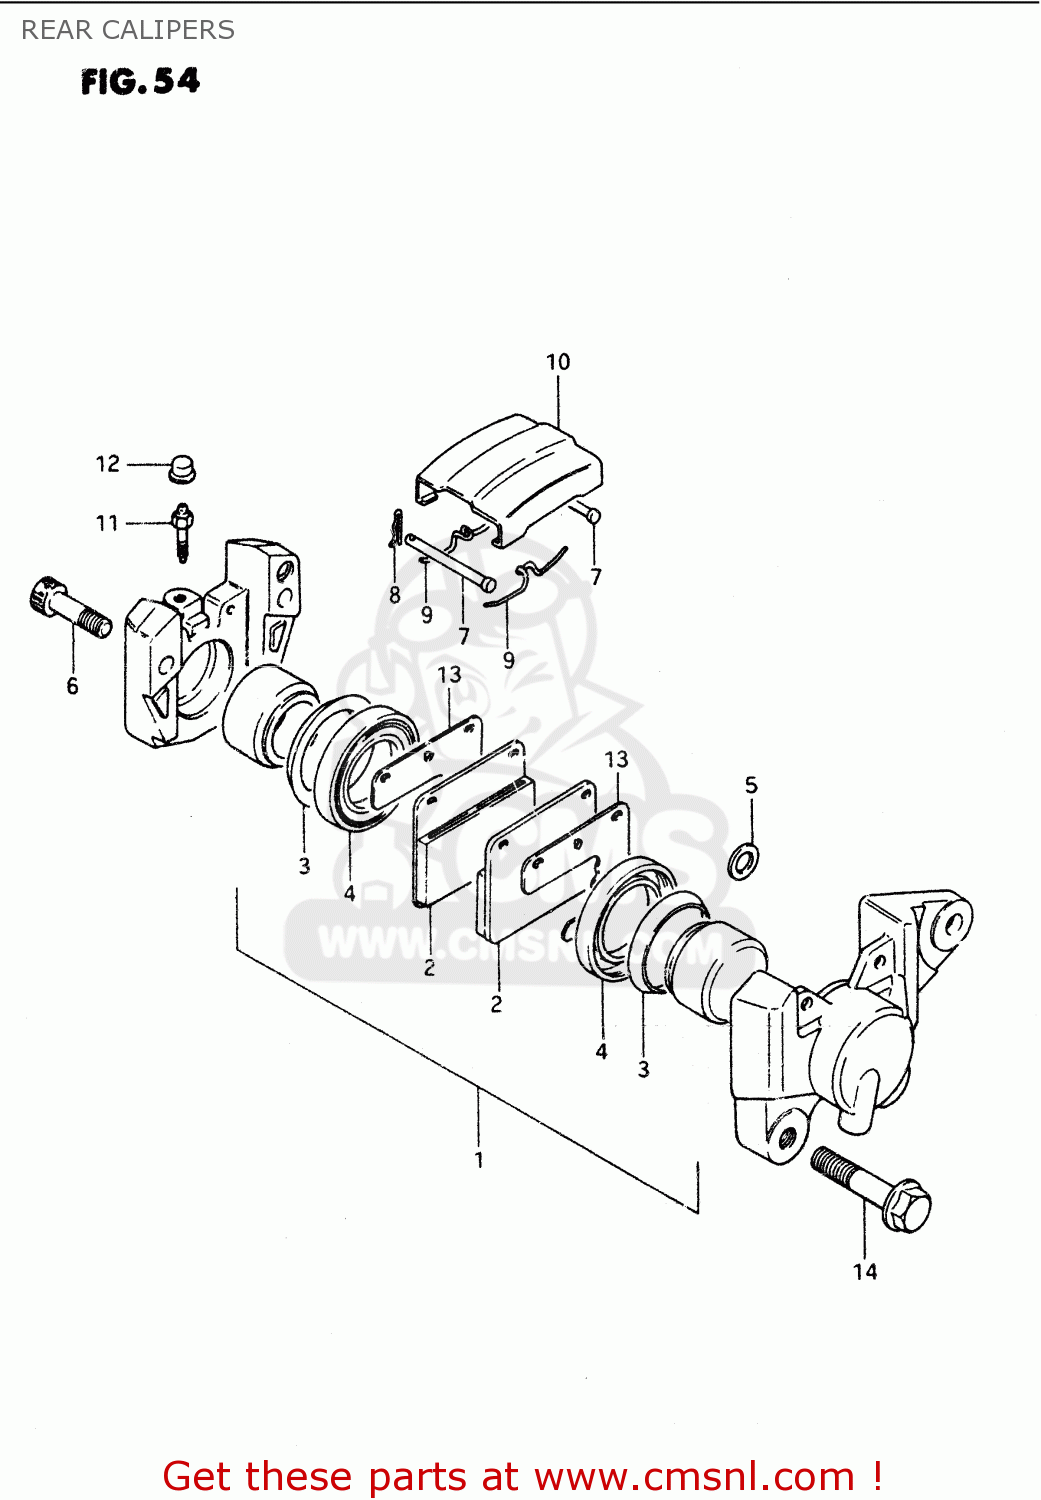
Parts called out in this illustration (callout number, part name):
1	PISTON SET
2	PAD,BRAKE (MCA)
3	SEAL,PISTON
4	BOOT,PISTON
5	SEAL,JOINT
6	BOLT,CALIPER HOUSING
7	PIN,PAD
8	CLIP,PAD PIN
9	SPRING
10	COVER,DUST
11	BLEEDER
12	CAP,BREATHER
13	SHIM,RR CALIPER
14	BOLT
